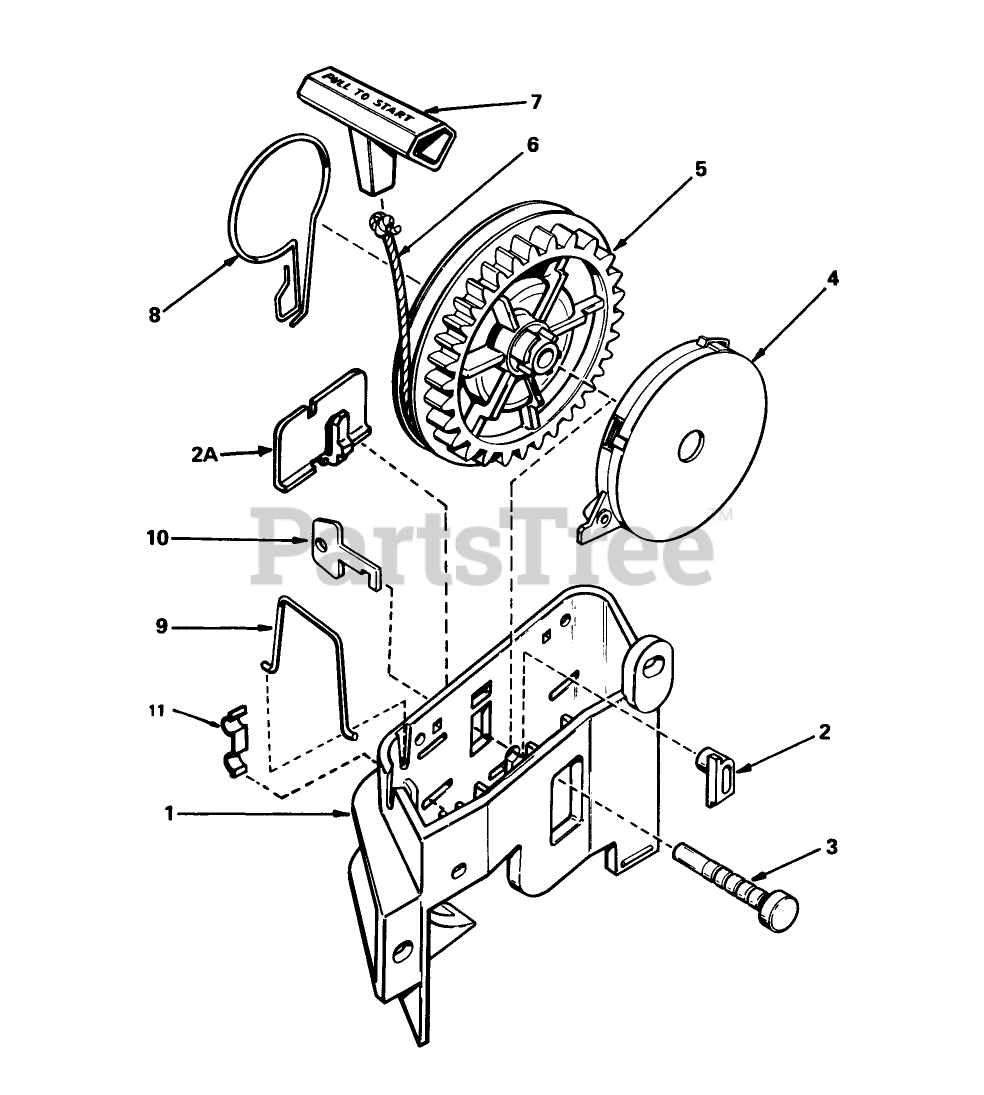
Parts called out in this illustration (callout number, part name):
1	Bracket Starter
2	Pawl, Locking Not used on all engine models)
2A	Clip, Starter Bracket (Used On Starters Not Equipped With Pawl, Ref. No. 2)
3	Pin-Pulley
4	Spring Assy., Rewind (Incl. Ref. #3)
6	Rope Starter (Length 65" & 9/64" Dia.)
7	Handle-Starter
9	Clip-Rope
10	Key (Not Used On All Engine Models
11	Washer-Thrust
